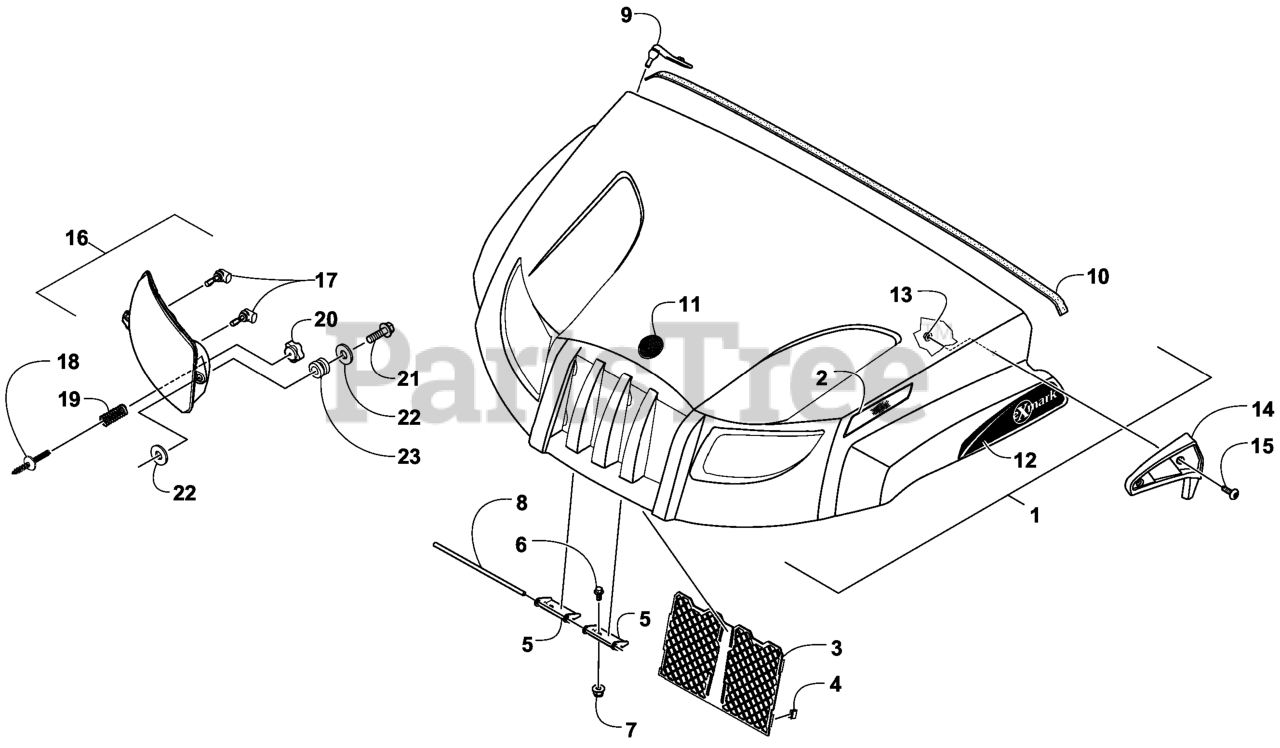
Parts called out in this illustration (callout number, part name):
2	REFLECTOR-FRONT, RH
2	REFLECTOR-FRONT, LH
3	GRILL-SCREEN
4	CLIP-U TYPE
5	BRACKET-HOOD HINGE
6	SCREW-HFH
7	NUT-HHF, LOCK, (NI)
8	PIN-HOOD
9	STRAP-HOLDDOWN, HOOD
10	SEAL-HOOD
11	DECAL-EXMARK
12	DECAL-BOX HOOD, RH
12	DECAL-BOX HOOD, LH
13	LINKAGE,LOWER CALIPER RH
14	LOUVER-HOOD, RH
14	LOUVER-HOOD, LH
15	SCREW-SHOULDER
16	HEADLIGHT-RH
17	BULB-HEADLIGHT
18	STUD-DOUBLE END
19	SPRING-ADJUSTMENT, HEADLI
20	KNOB-ADJUSTMENT
21	BELLCRANK ASM
22	WASHER-FLAT
23	GROMMET-GAUGE MOUNT
